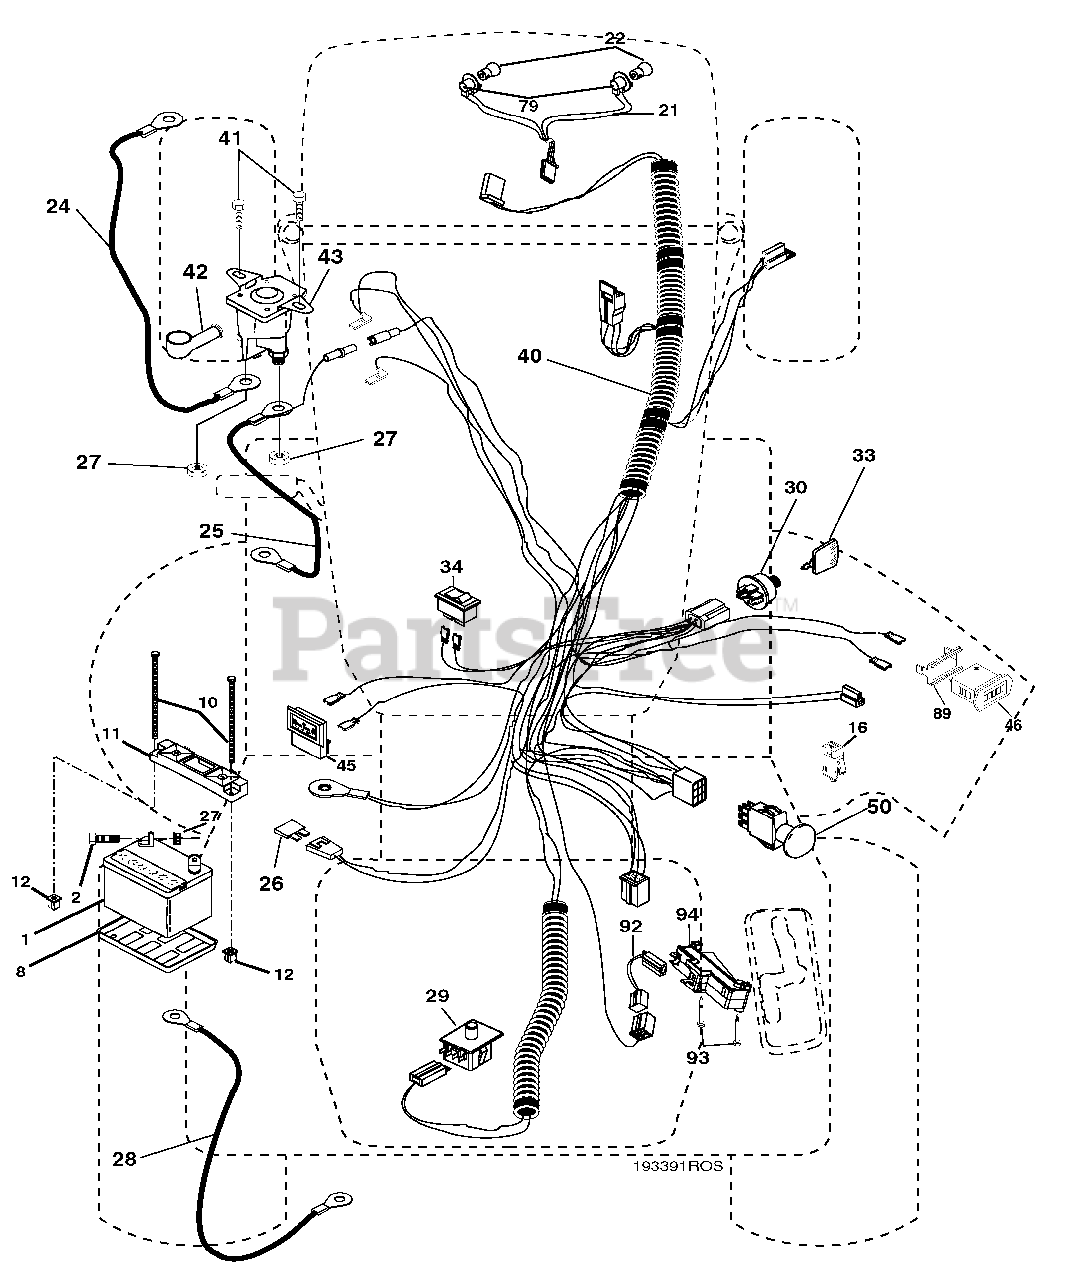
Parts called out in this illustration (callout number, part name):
1	Battery
2	Bolt Hex Head 1/4-20 x 3/4
8	Tray, Bat tery
10	Bolt Btr Frt 1/4-20 x 7.5 zinc
11	Holdown Battery Front Mount
12	Nut Push Nylon 1/4"
16	Switch Interlock Push-In
21	Harness Headlight w/Bulbs
22	Bulb Light
24	Cable, Battery
25	Cable, Battery
26	Fuse
27	Nut Keps Hex 1/4-20 unc
28	Cable, Ground
29	Switch, Seat
30	Switch, Ign
33	Key
34	Switch light
40	Harness, Ignition
41	Screw 1/4-20 x 1/2
42	Cover, Terminal Red
43	Solenoid
45	Ammeter
46	Hourmeter Snap-In
50	Switch, PTO
79	Socket, Light Bulb
89	Bracket Snap-In
92	Harness Pigtail Reverse Switch
93	Screw Plastite 10-14 x 2.0
94	Modual Reverse ROS
